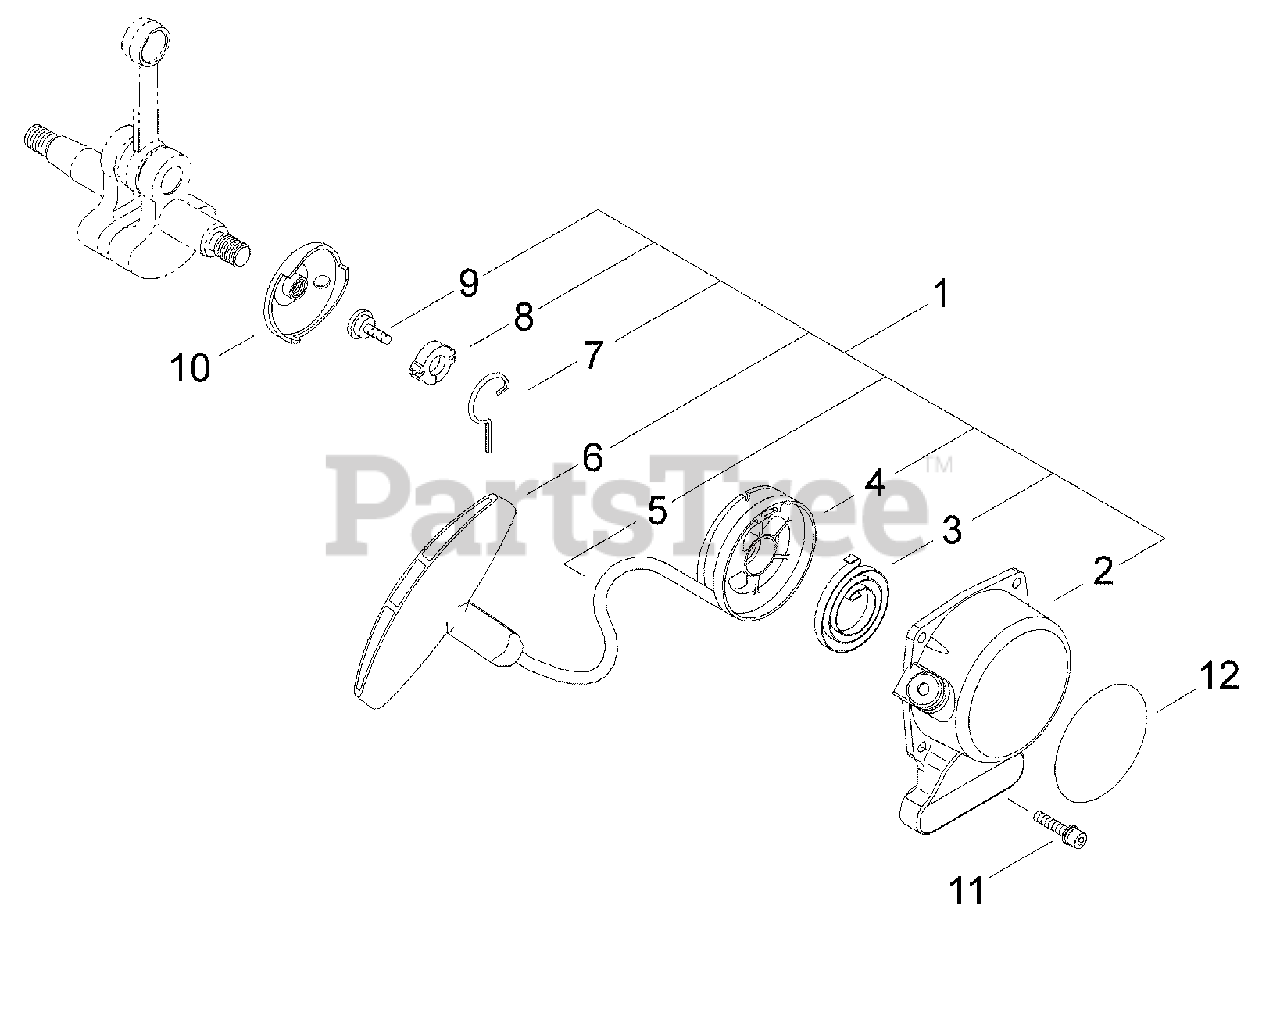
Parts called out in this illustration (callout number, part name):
1	STARTER ASSY
2	CASE, STARTER
3	SPRING, REWIND
4	REEL, ROPE
5	ROPE, STARTER
6	GRIP, STARTER
7	PAWL, STARTER
8	WASHER - 5
9	SCREW - 5
10	STARTER PAWL ASSY
11	SCREW - 4X14
12	LABEL - E4
